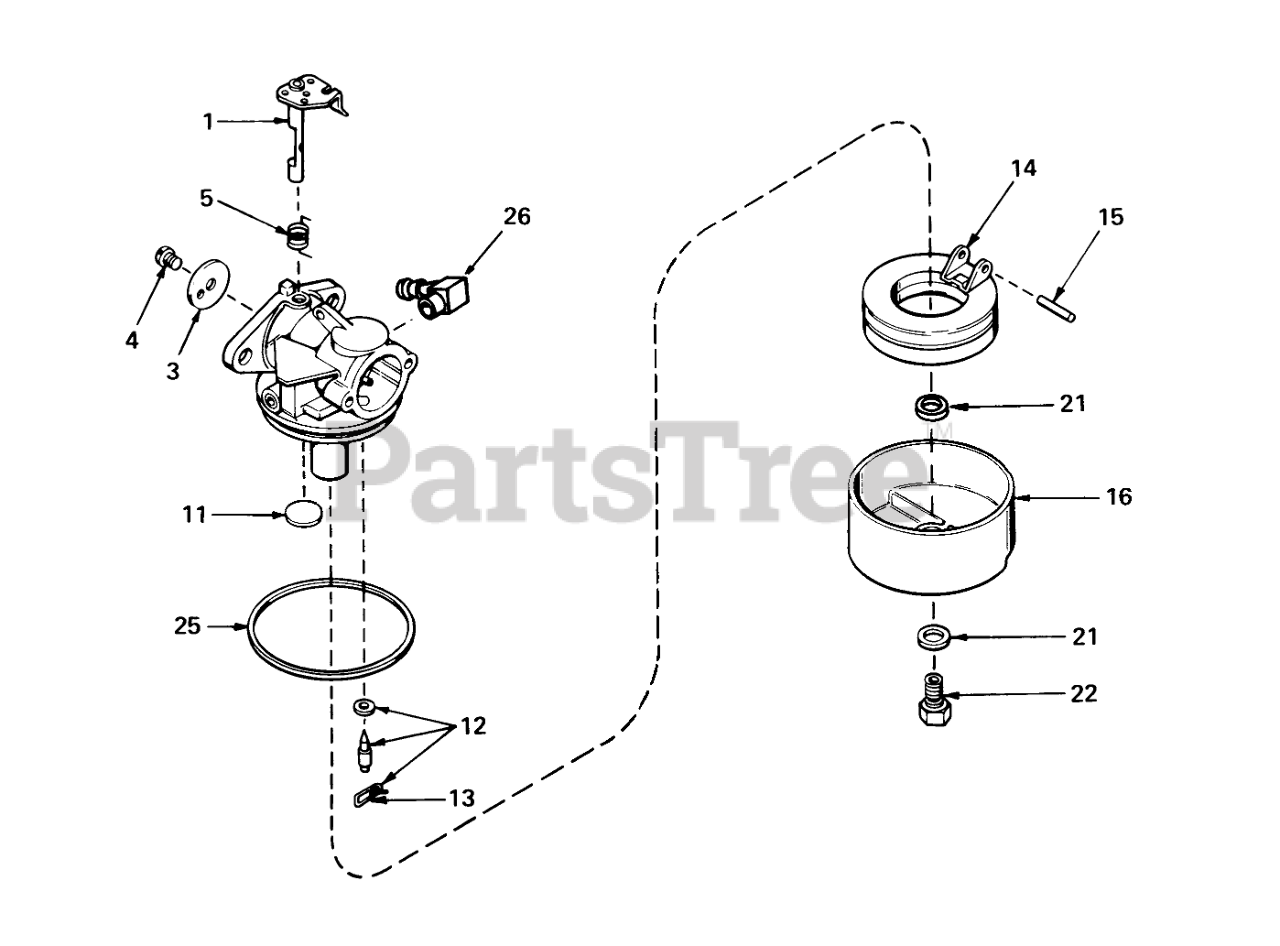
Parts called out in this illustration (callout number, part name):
1	Throttle Shaft and Lever ASM
3	Throttle-Shutter
4	Screw-Shutter
5	Spring, Return
11	Plug-Welch, Atmospheric Vent
12	Inlet Needle, Seat & Clip Assy. (Incl. No. 13)
13	Clip-Spring
14	Float,Carburetor
15	Shaft-Float
16	Bowl Float
21	Gasket-Bowl
22	Nut, Float Bowl
25	O Ring-Bowl, Float
26	Fitting-Fuel
